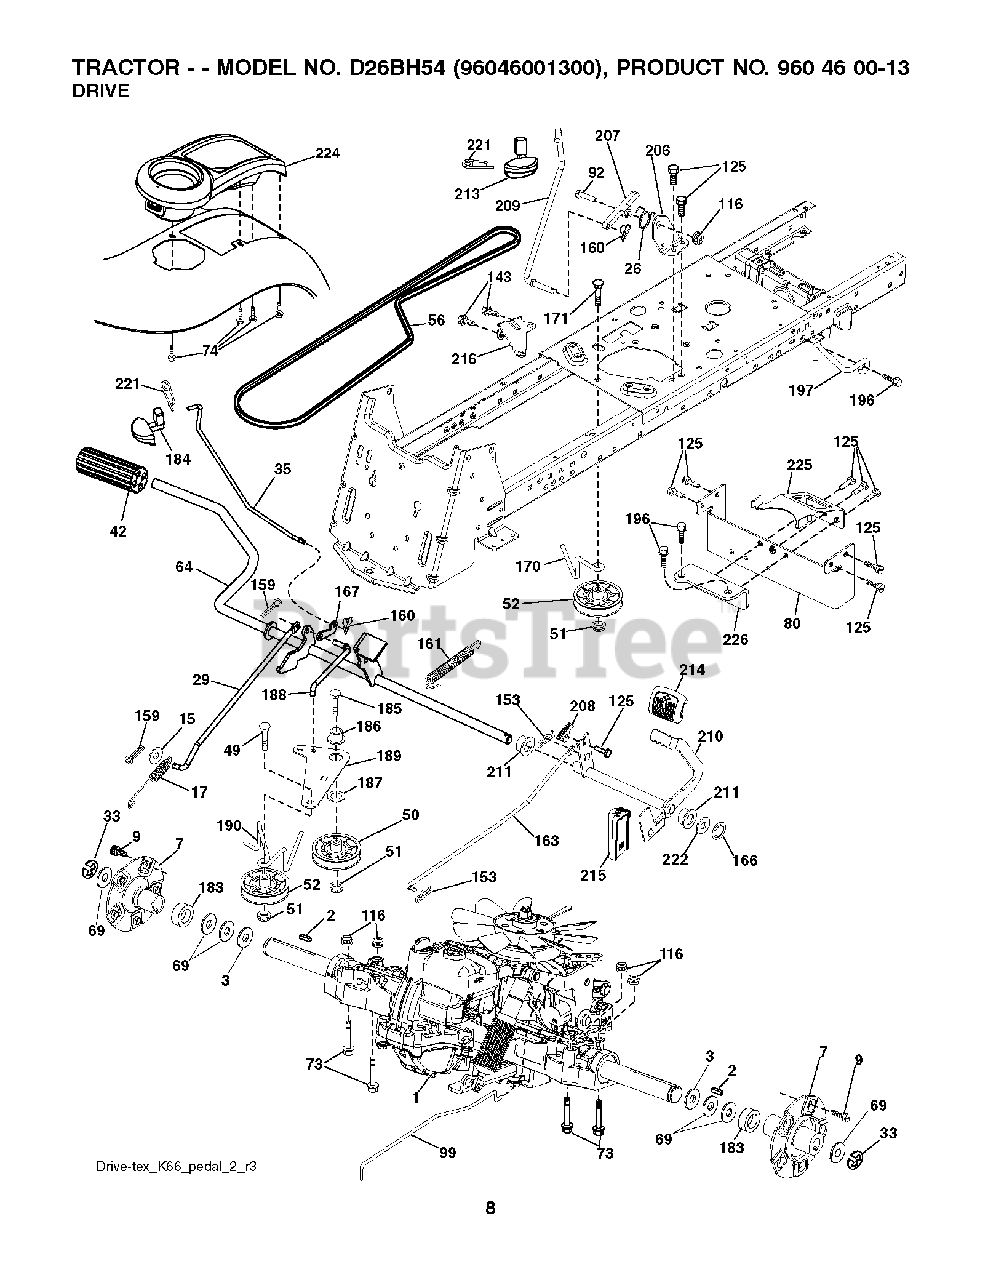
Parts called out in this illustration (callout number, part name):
2	KEY 1/4 X 2.5
3	WASHER T
7	HUB.ASM.WHEEL.REAR.23"TEX
9	HUB BOLT
15	WASHER
17	SPRING.BRAKE.K46
26	SPRING.RETURN.CRUISE
29	ROD.BRAKE.K66
33	E RING HYT
35	ROD.BRAKE.PARKING.STEALTH
42	Pedal Cover
50	IDLER.FLAT.910.OFFSET
51	NUT LOCK FLG 3/8-16 UNC
52	IDLER.V-GROOVE.910.OFFSET
64	SHAFT.ASM.PEDAL.BRK.CNTR
73	BOLT HEX 5/16-18 GR 5
74	SCREW.HI-LO.CONSOLE
80	STRAP.TORQUE.K66
92	BOLT
99	ROD.SPRING.BYPASS.K66.GT.Z
116	NUT LOCK HEX FLANGE 5/16-18
125	SCREW
143	SCREW LT
153	Retainer, M
159	COTTER PIN
160	RETAINER CLIP
161	SPRING, RETURN LT
163	ROD.PEDAL.CONTROL
166	NUT.PUSH.625
167	LATCH.BRAKE.SPRING
170	KEEPER.V-IDLER.CENTER.
183	SPACER.AXLE.HG.TEX
184	HANDLE.PRKG.BRAKE.STLTH.TX.RED
186	SPACER.RETAINER
187	WASHER 12/32X2X10GA
188	LINK.CLUTCH.GROUND.DRIVE
189	BELLCRANK.GROUND.DRIVE.TEX.
190	KEEPER.BELLCRANK.DRIVE
196	SCREW 3/8-16X1
197	BRKT.ANIT-ROTATION.CLUTCH
206	BRKT.MOUNT.LATCH.CRUIS
207	LATCH.CONTROL.CRUISE
208	GEAR.SECTOR.CONTROL.CR
209	ROD.CONTROL.CRUISE.STEALTH.TEX
210	ROCKER.ASM.PEDAL.CONTR
211	BEARING.NYLON
213	KNOB.CONTROL.CRUISE
214	PEDAL.FORWARD.PAD.TEX
215	PEDAL.REVERSE.TEX.GT.4
216	BRACKET.PULLEY.IDLER.W/TEX
221	RETAINER.SPRING.CLIP.H
222	WASHER 21/32 X 1-1/4 X 10 GA.
224	CONSOLE.TOOLBOX.PCH.ERGO.BLACK
225	KEEPER.BELT.TRANSAXLE.K66
226	BRACKET.MOUNT.TORQUE.K66.TG
